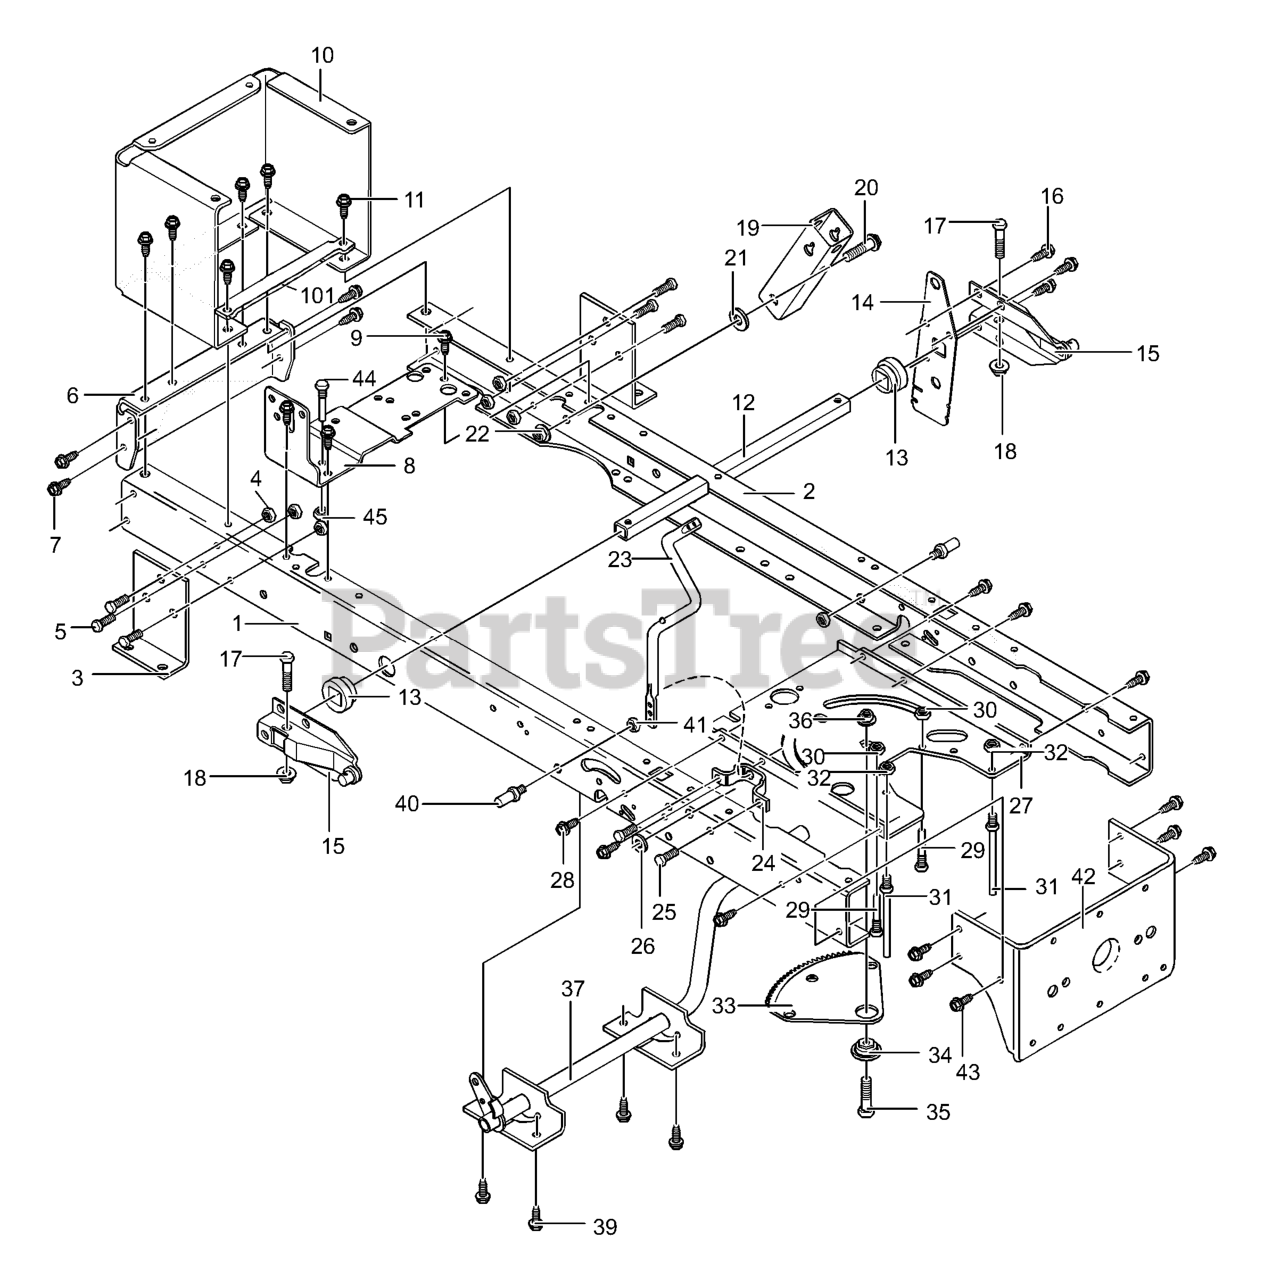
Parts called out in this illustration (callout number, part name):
1	Frame, Rail RH
2	Frame, Rail LH
3	Bracket, Transaxle
4	Nut, .32-18 Flange Ctrlk
5	Screw, .312-18x.75
6	Hitch Plate
7	Screw , .312-18x.75
8	Bracket, Shift RH
9	Screw , .312-18x.75
10	Rear Panel
11	Screw , .312-18x.75
12	Lifter Tube
13	Bushing, Lift Arm
14	Plate, Lift Arm
15	Lever, Lift Arm
16	Screw .31x.50
17	Screw, .5/16-21x1.25
18	Nut, .32-24 Flangelock
19	Pivot Bracket
20	Bolt, 3/8 HHSH
21	Flat washer
22	Nut, .38-16 Flange Ctrlk
23	PTO Crank
24	Bracket, Bell Crank
25	Screw, .312-18x.75
26	Flat washer
27	Steering Plate
28	Screw, .312-18x.75
29	Screw Guide 5/16-18
30	Nut, .32-18 Flangelock
31	Screw Guide
32	Nut, .32-18 Flangelock
33	Gear Sector
34	Bearing, Sector Gear
35	CAPSCREW, Hex Head, 5/16-18 x 1
36	Nut, 5/16 Hkeps
37	Asm. Brake Pedal
39	Screw, .312-18x.75
40	Pin, Threaded Shoulder
41	Nut, 3/8-16 Hwdfl Whiz
42	Bracket, Hanger Rear
43	Screw, .312-18x.75
44	Screw Guide 5/16-18
45	Nut, .32-18 Flangelock
93	Flat washer
101	Bracket, Battery Support
